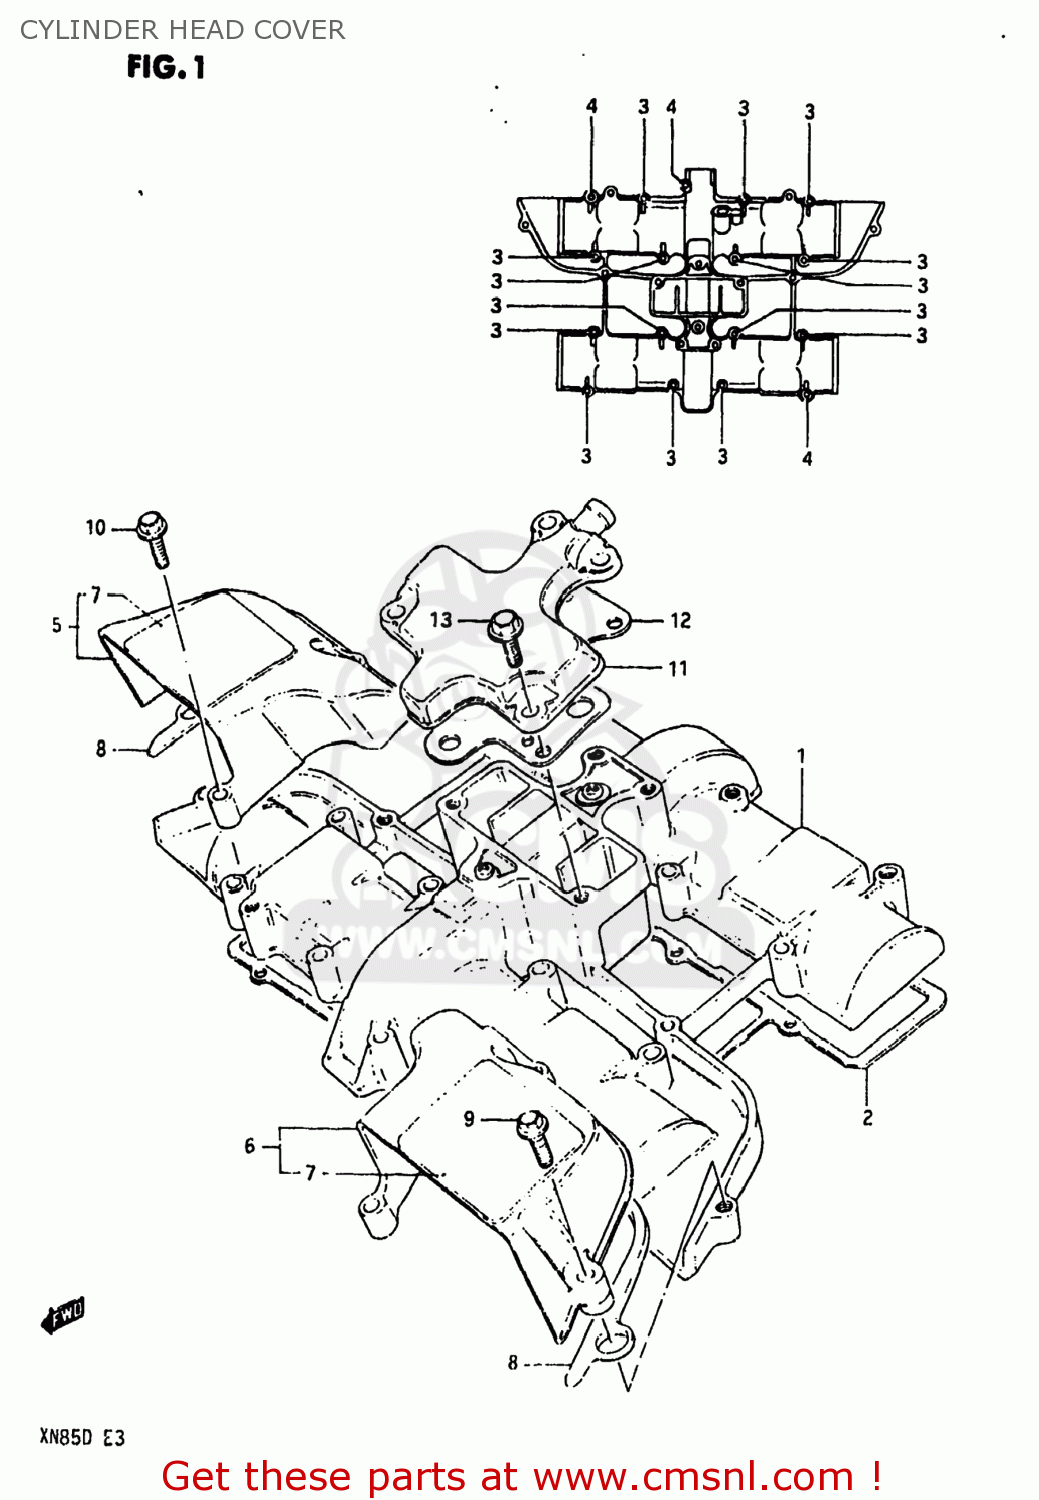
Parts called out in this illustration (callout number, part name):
1	COVER,CYLINDER HEAD
2	GASKET,CYLINDER HEAD COVER (MCA)
3	BOLT
4	BOLT,UNDER
5	COVER,AIR GUIDE,RIGHT
6	CYLINDER
7	CAP,CYLINDER COVER NO
8	CUSHION
9	BOLT
10	BOLT 6X35
11	COVER,BREATHER
12	GASKET (MCA)
13	BOLT,REAR
